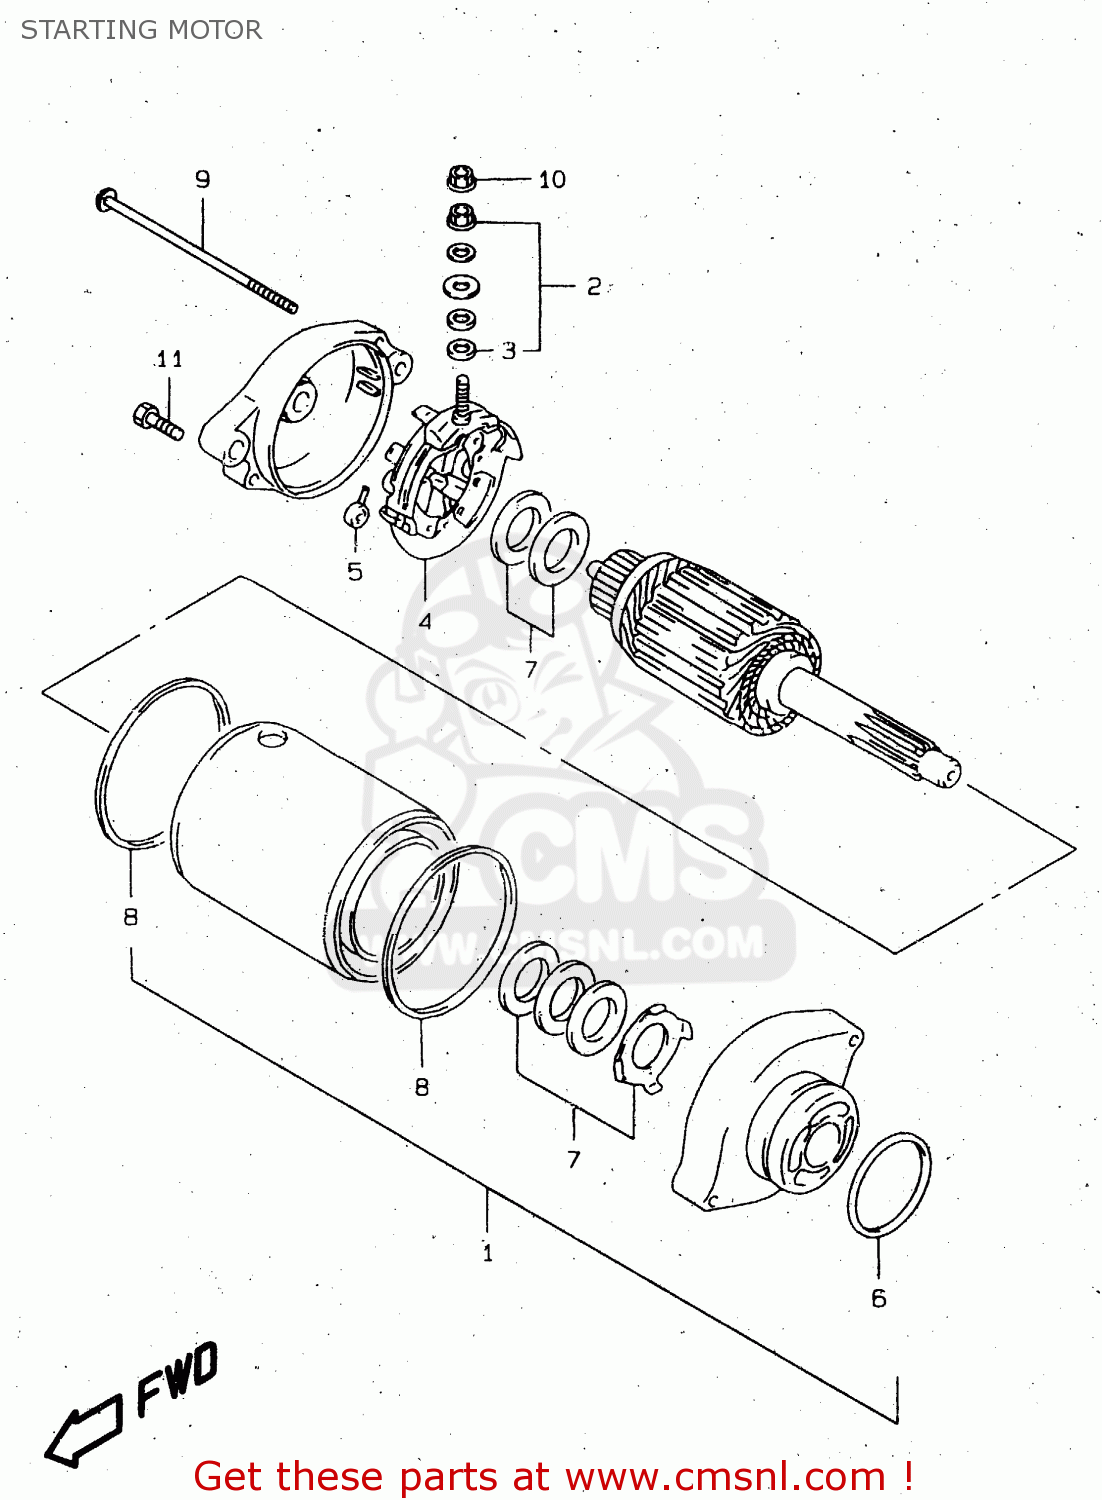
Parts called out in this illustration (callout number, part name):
1	MOTOR ASSY,STARTING
2	TERMINAL SET,BRUSH
3	O RING
4	HOLDER SET,BRUSH
5	SPRING,BRUSH
6	O RING
7	WASHER SET
8	SQUARE RING
9	BOLT
10	NUT
11	BOLT,G/S SWITC
